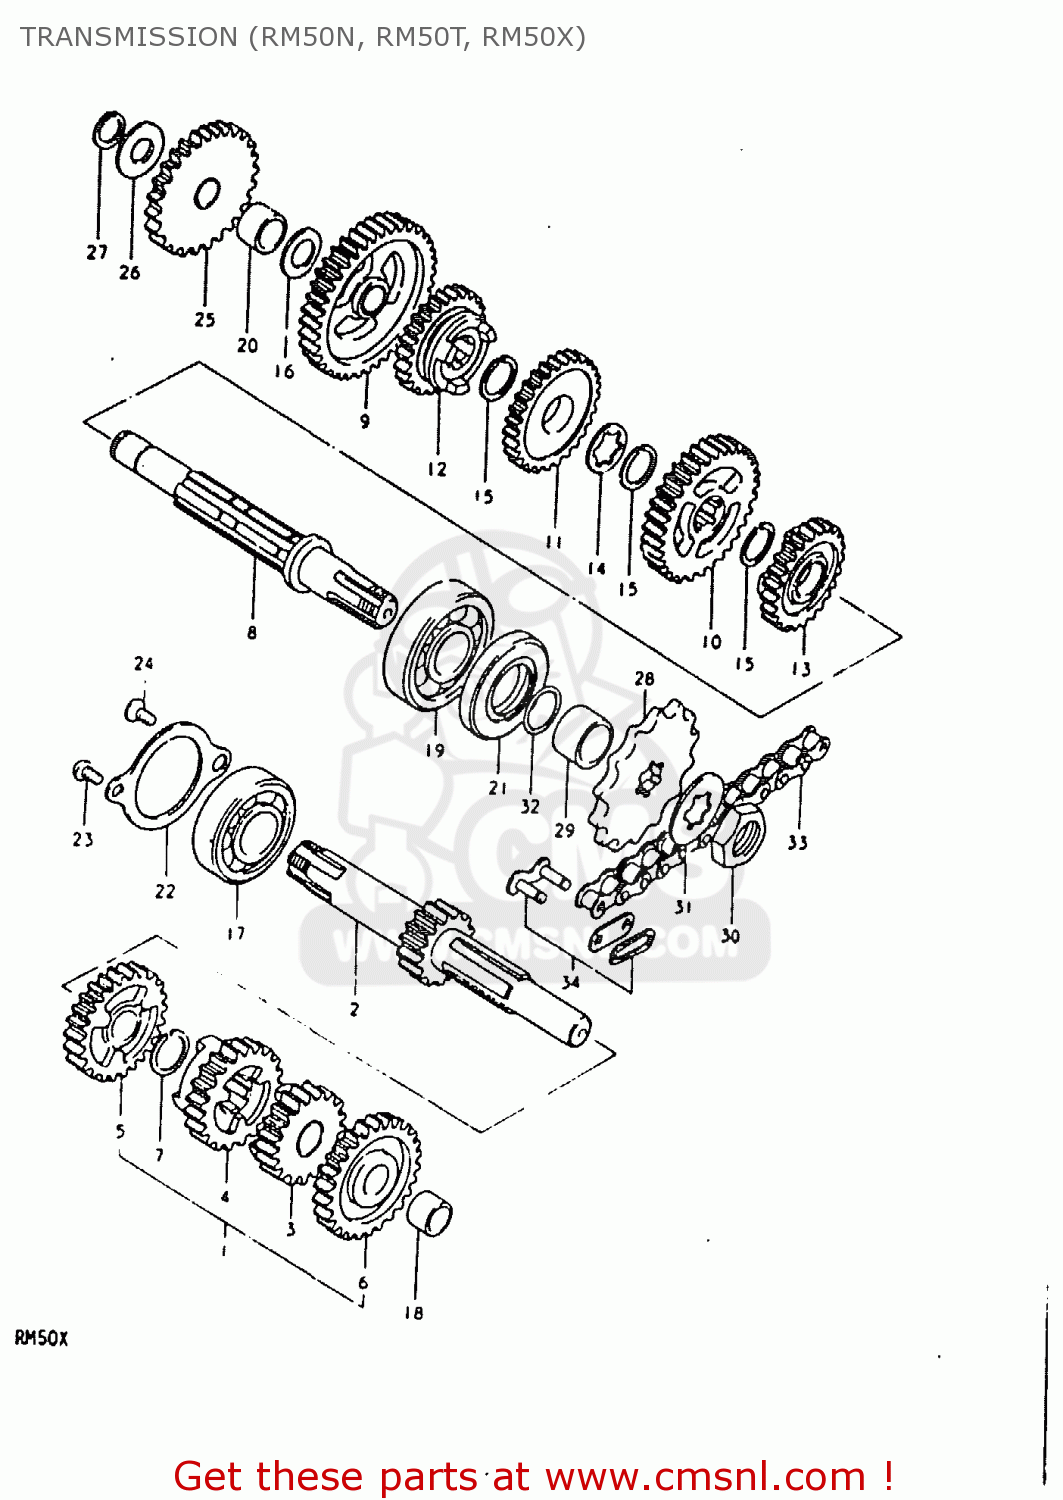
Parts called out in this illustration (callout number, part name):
1	SHAFT,COUNTER
2	SHAFT,COUNTER(NT:13)
3	GEAR,2ND DRIVE(NT:19)
4	GEAR,3RD DRIVE(NT:22)
5	GEAR,4TH DRIVE(NT:24)
6	GEAR,FIFTH DRIVE
7	CIRCLIP
8	SHAFT,DRIVE
9	GEAR,1ST DRIVEN(NT:35)
10	GEAR,2ND DRIVEN(NT:32)
11	GEAR,3RD DRIVEN(NT:29)
12	GEAR,4TH DRIVEN(NT:36)
13	GEAR,5TH DRIVEN(NT:24)
14	WASHER(13X24X1)
15	CIRCLIP
16	WASHER,LOCK
17	BEARING
18	BUSH
19	BEARING
20	BUSH
21	SEAL,OIL(21X40X6)
22	RETAINER,CNTR SHAFT BEARING
23	SCREW
24	SCREW
25	GEAR,KICK STARTER IDLE
26	WASHER
27	CIRCLIP
28	SPROCKET,ENGINE
29	SPACER(17X21X13)
30	NUT
31	WASHER,LOCK
32	O RING(D:1,ID:16.8)
33	CHAIN ASSEMBLY,DRIVE
34	JOINT ASSEMBLY,CHAIN
